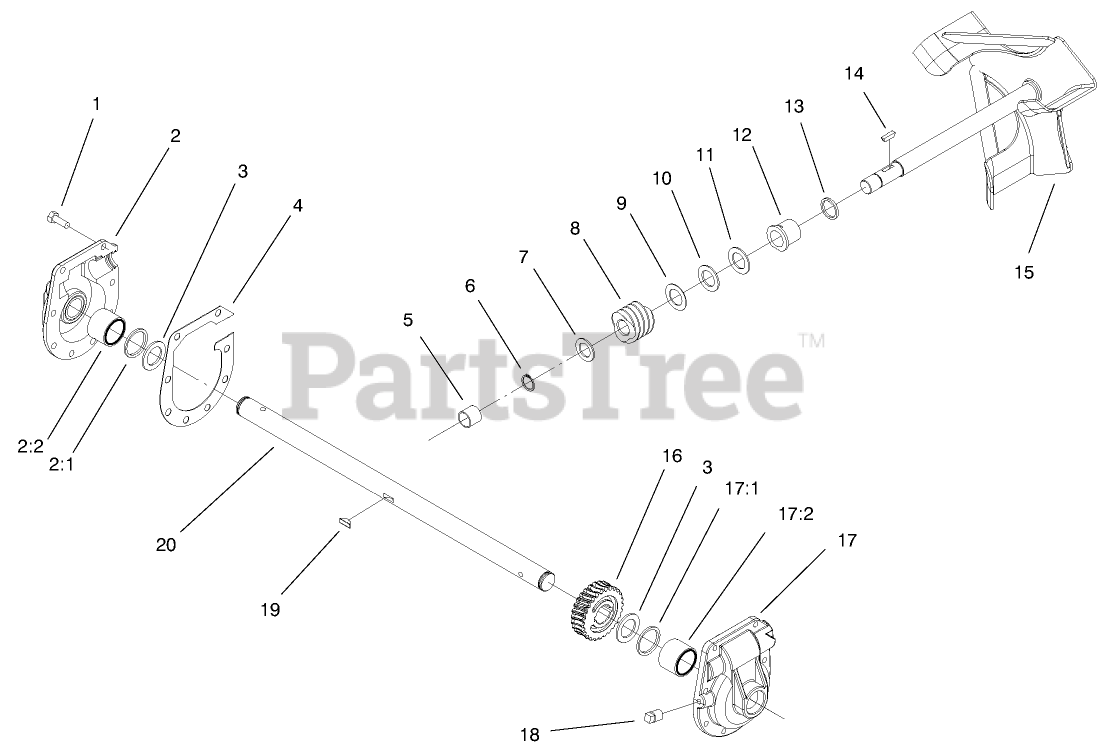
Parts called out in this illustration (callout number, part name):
1	SCREW-TAPTITE
2	RH BUSHING CASE ASM
2:1	SEAL-OIL
2:2	BUSHING
3	WASHER-THRUST
4	GASKET-CASE, GEAR
5	BUSHING
6	RING-SNAP
7	WASHER-THRUST
9	WASHER-THRUST
10	BEARING-THRUST
11	WASHER-THRUST
12	BUSHING-INPUT
13	RING-QUAD
14	KEY-WOODRUFF
15	IMPELLER SHAFT ASM
16	GEAR-WORM, 27T
17	LH BUSHING CASE ASM
17:1	SEAL-OIL
17:2	BUSHING
18	PLUG-PIPE, SQH
19	KEY-WOODRUFF
20	SHAFT-AUGER
